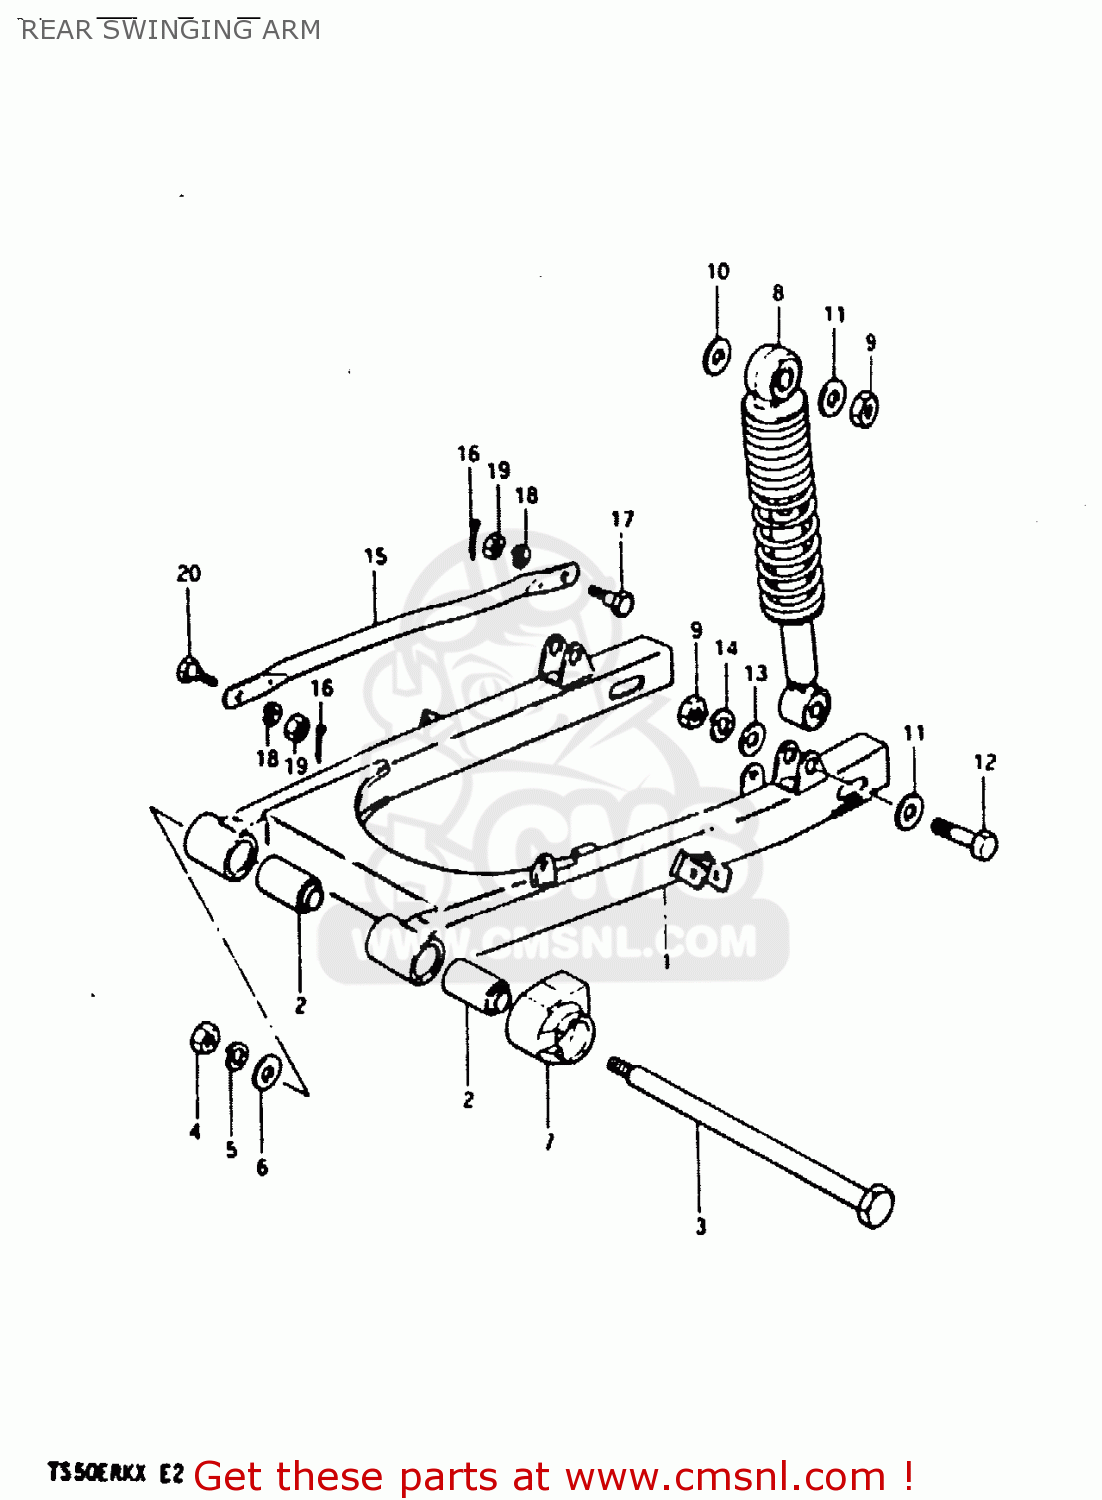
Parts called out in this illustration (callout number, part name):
1	SWINGING ARM, REAR
2	BUSH
3	SHAFT,REAR SWING ARM
4	NUT
5	LOCK WASHER
6	WASHER
7	BUFFER
8	SHOCK ABSORBER, REAR
9	NUT
10	WASHER
11	WASHER
12	BOLT(10X36)
13	WASHER
14	LOCK WASHER
15	TORQUE LINK, REAR
16	PIN
17	BOLT(8X26.5)
18	LOCK WASHER
19	NUT
20	BOLT(8X22)
